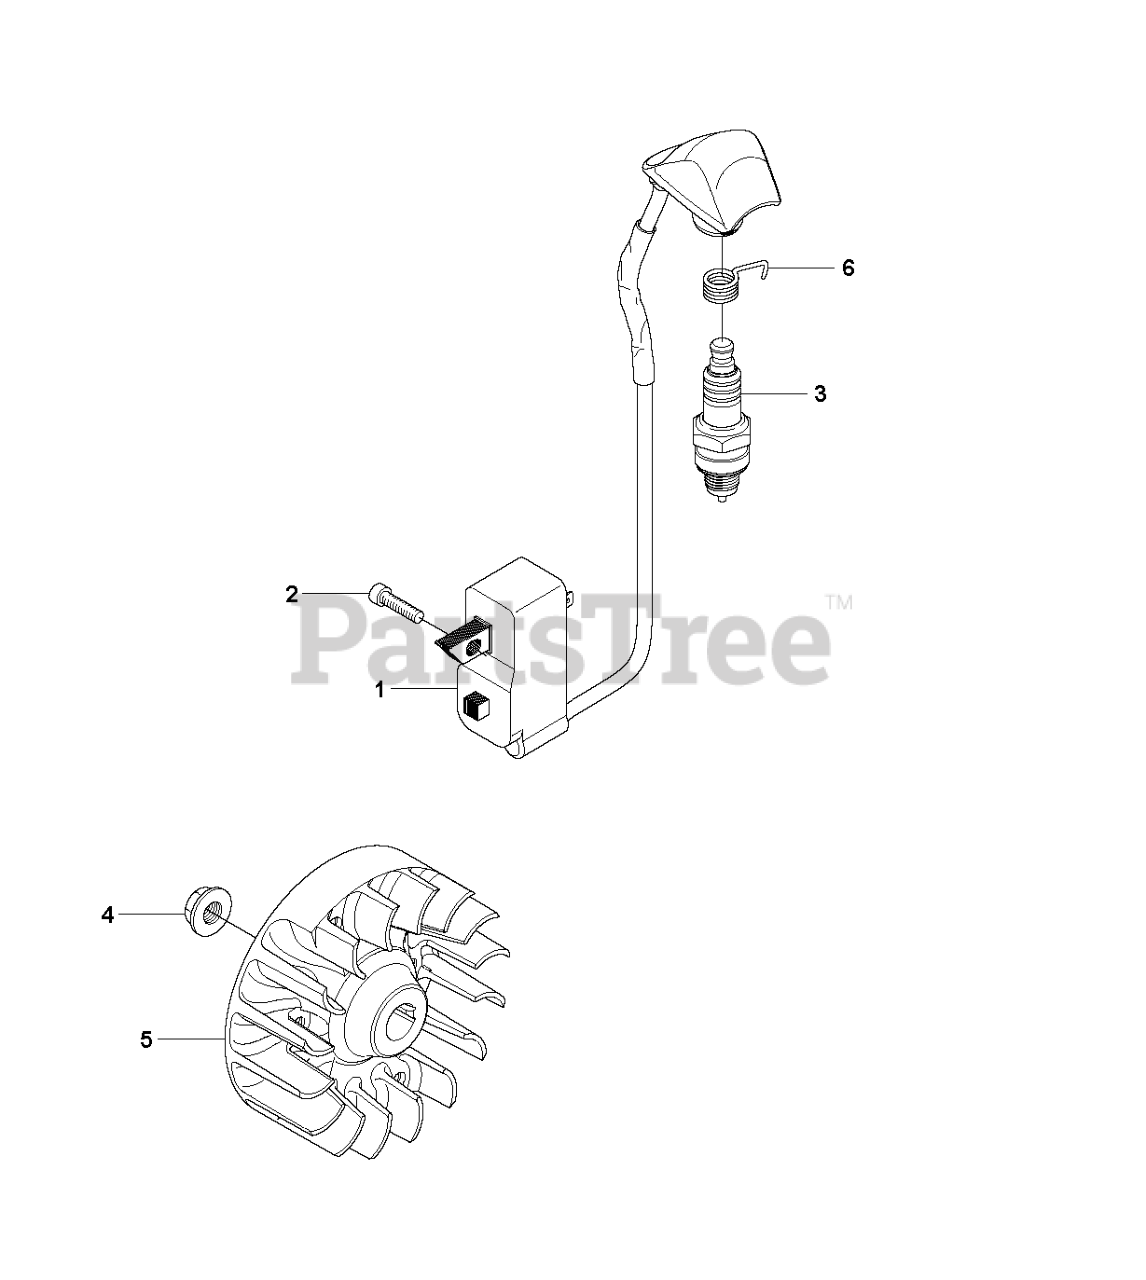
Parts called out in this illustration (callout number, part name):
1	IGNITION MODULE DM60CWS
3	SPARK PLUG M14X1.25 NGK BPMR7A
4	FLANGE NUT
5	FLYWHEEL
6	SPRING
